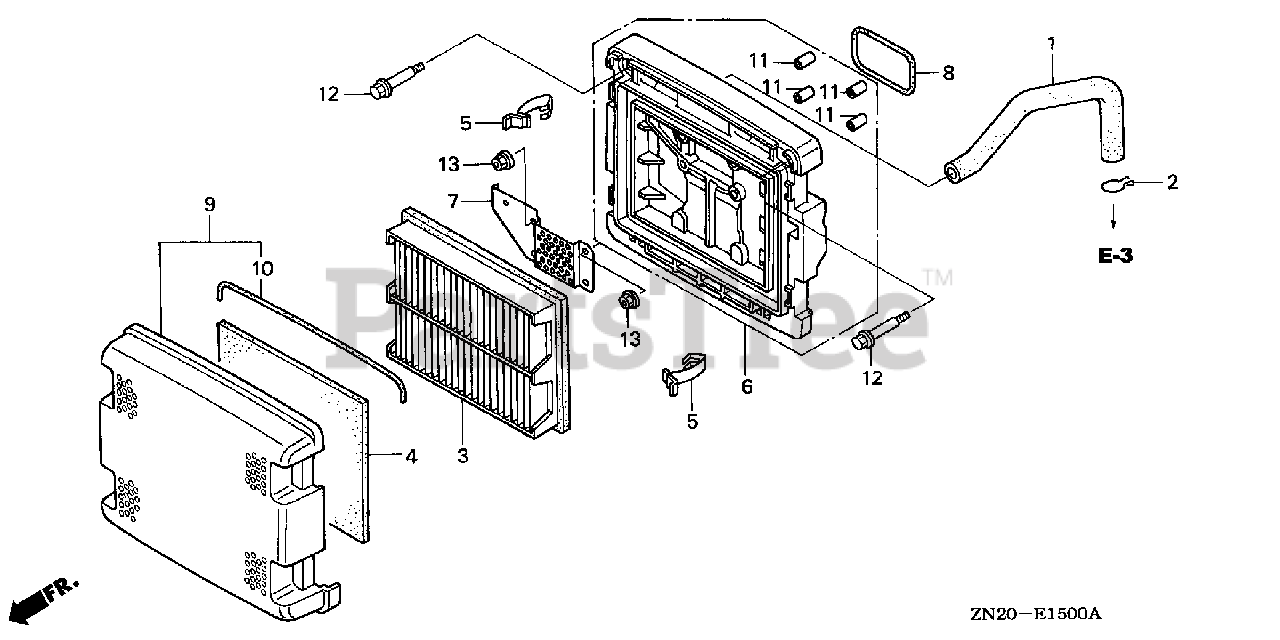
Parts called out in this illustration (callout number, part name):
1	TUBE, BREATHER
2	CLIP, BREATHER TUBE
3	ELEMENT, AIR CLEANER
4	FILTER (OUTER)
5	CLIP, AIR CLEANER
6	HOUSING, AIR CLEANER
7	CAP, AIR CLEANER
8	GASKET, AIR CLEANR
9	COVER ASSY., AIR CLEANER
10	SEAL, AIR CLEANER COVER
11	COLLAR A, AIR CLEANER
12	BOLT, SPECIAL (5MM)
13	NUT, FLANGE (6MM)
